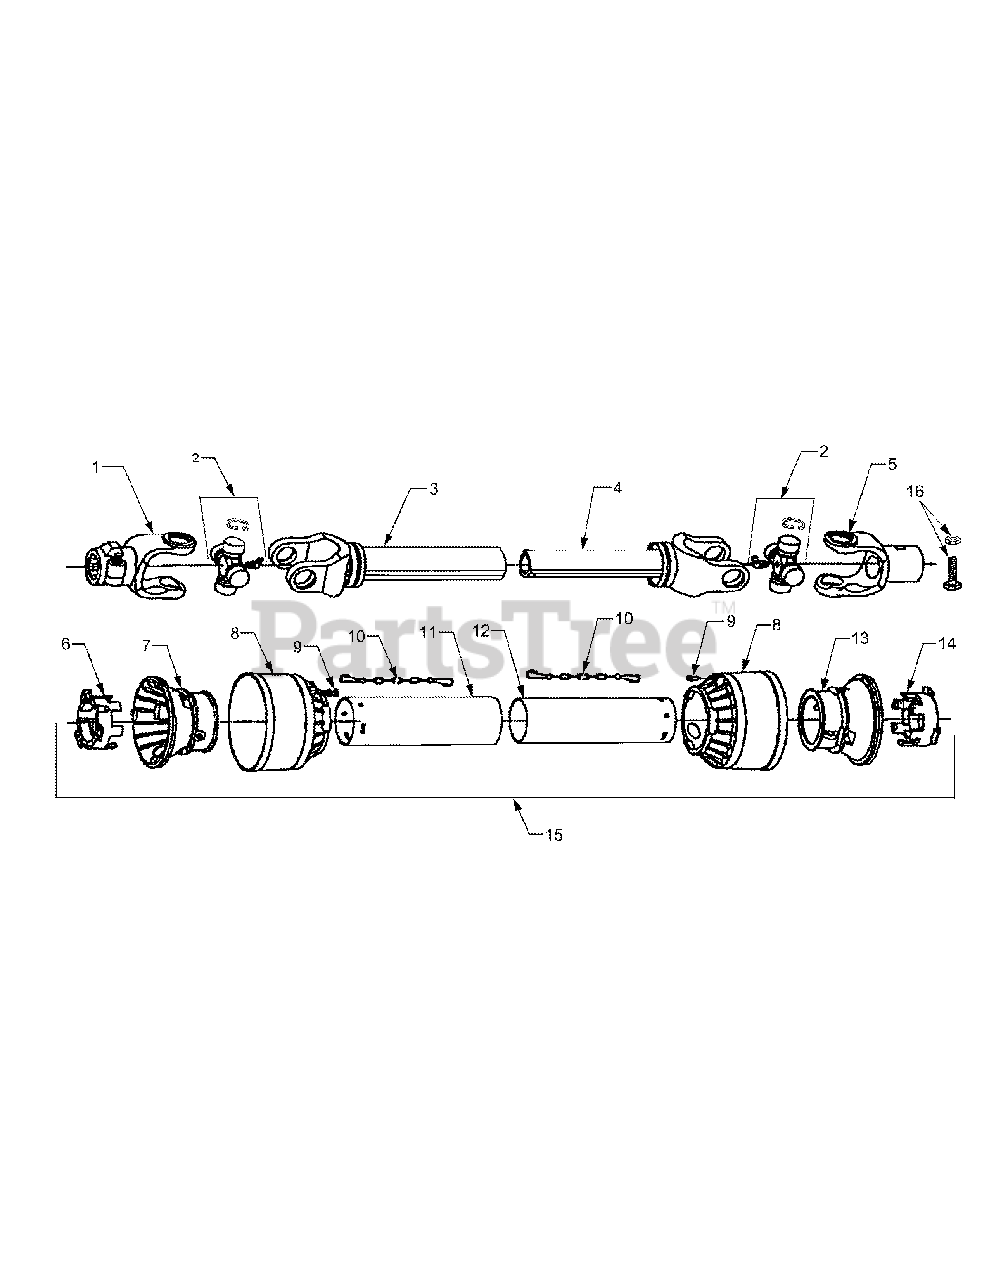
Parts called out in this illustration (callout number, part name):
1	Yoke, Tractor End
2	Cross Assembly
3	Outer Tube with Yoke
4	Inner Tube with Yoke
5	Yoke, Implement End
6	Tube Bearing, Outer
7	Outer Tube Rigid Cone
9	Rotation Stop Pin
13	Inner Tube Rigid Cone
14	Tube Bearing, Inner
15	Shield, Complete
16	Shear Bolt and Nut
